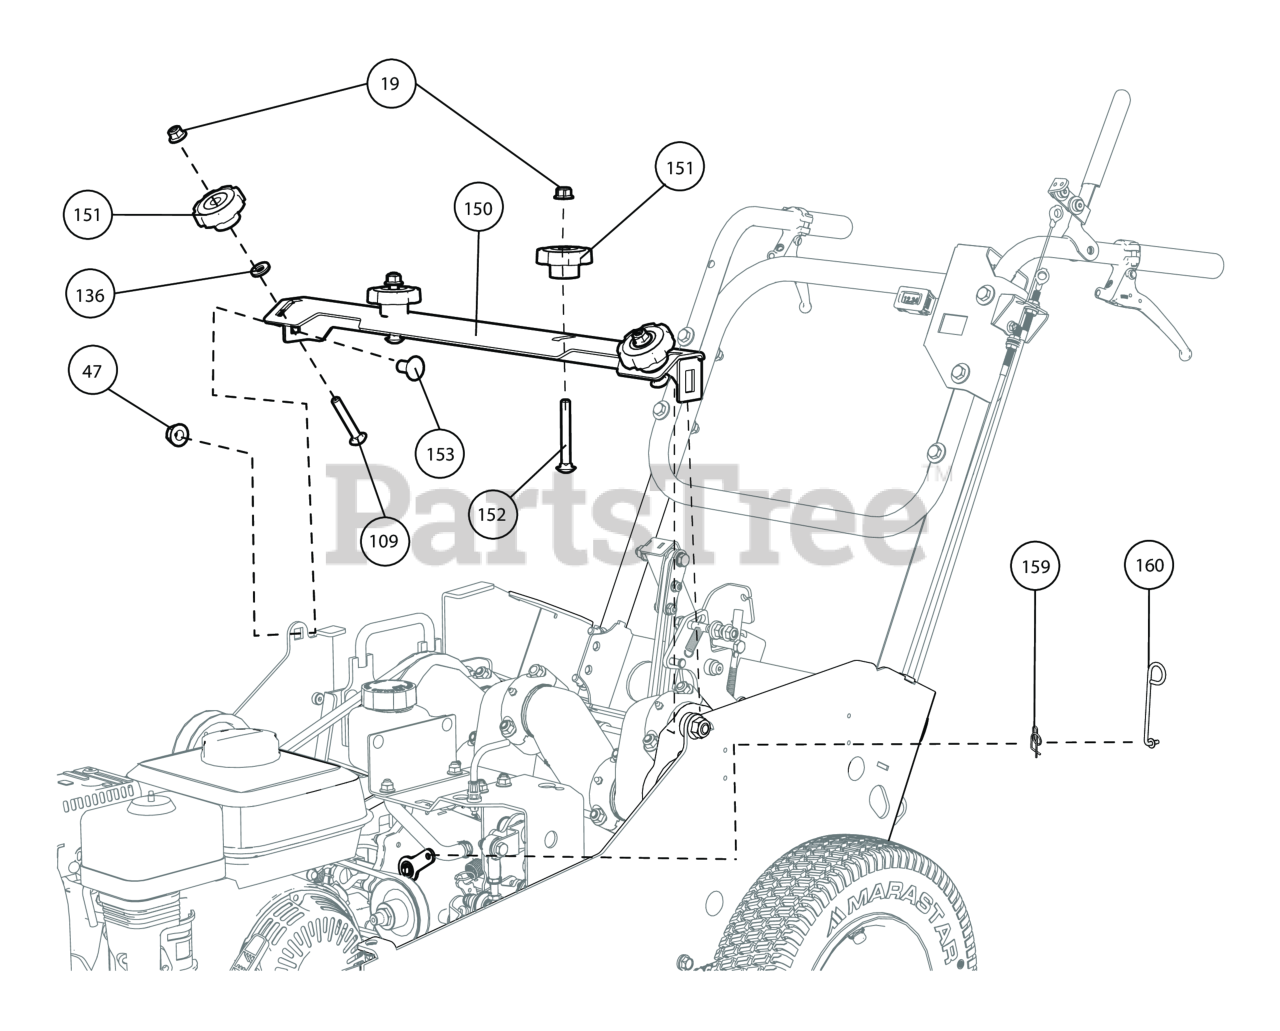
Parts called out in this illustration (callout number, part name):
19	NUT-HEX-NYLK, FLG .375"-16 ZP
47	NUT-HEX-NYLK, FLG .500"-13 ZP
109	BOLT CARRIAGE 3/8-16 X 2 1/2" ZP
136	WSHR-NYL, FLT, .385" X .880" X .125"
150	SUPPORT, SHIELD & TANK
151	KNOB 3/8-18, SOLID HUB
152	BOLT CARRIAGE 3/8-16 X 3" ZP
153	BLT-RDHDSQNK, .500"-13 X 1.000" G5 ZP
159	1/4" RUE RING
160	ROD, TRANSMISSION BYPASS
